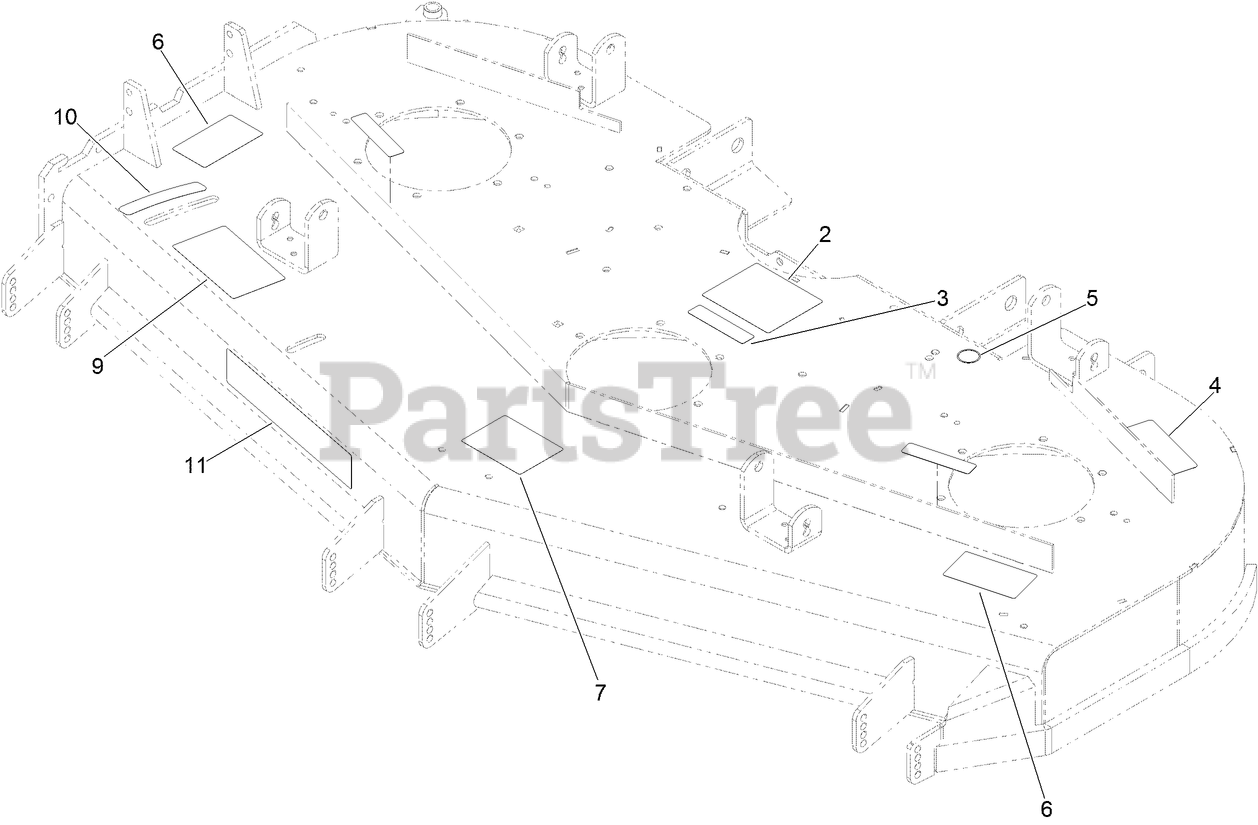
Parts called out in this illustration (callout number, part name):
2	DECAL-ROUTING, BELT
3	DECAL-WARNING
4	DECAL-TORQUE, BLADE BOLT
5	DECAL-GREASE
6	DECAL-DANGER
7	DECAL-ANTI SCALP
9	DECAL-ADJUSTMENT, BAFFLE
10	DECAL-SETTING, BAFFLE
